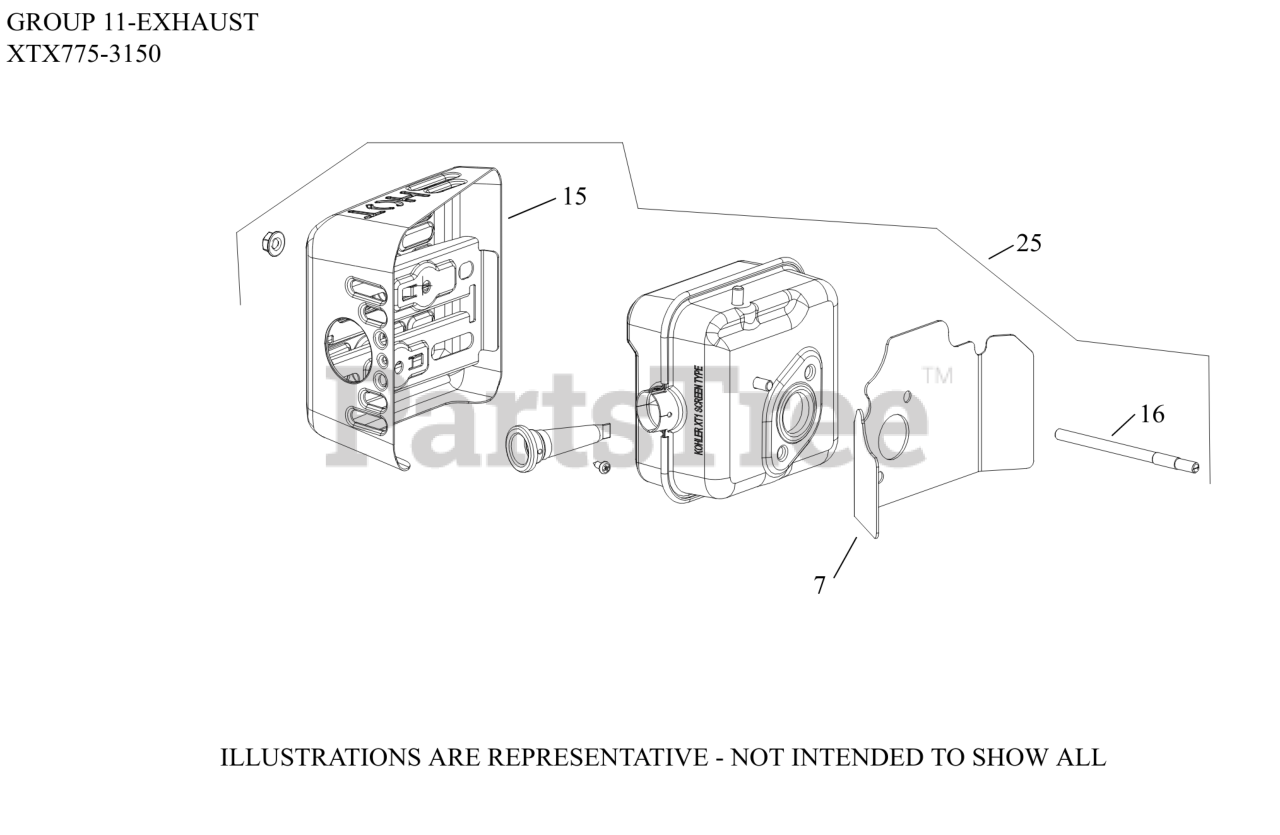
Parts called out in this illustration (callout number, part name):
7	GASKET, MUFFLER (HEAT DEFLECTOR)
15	GUARD, MUFFLER ASSEMBLY
16	STUD, EXHAUST (M6)
25	KIT, MUFFLER
